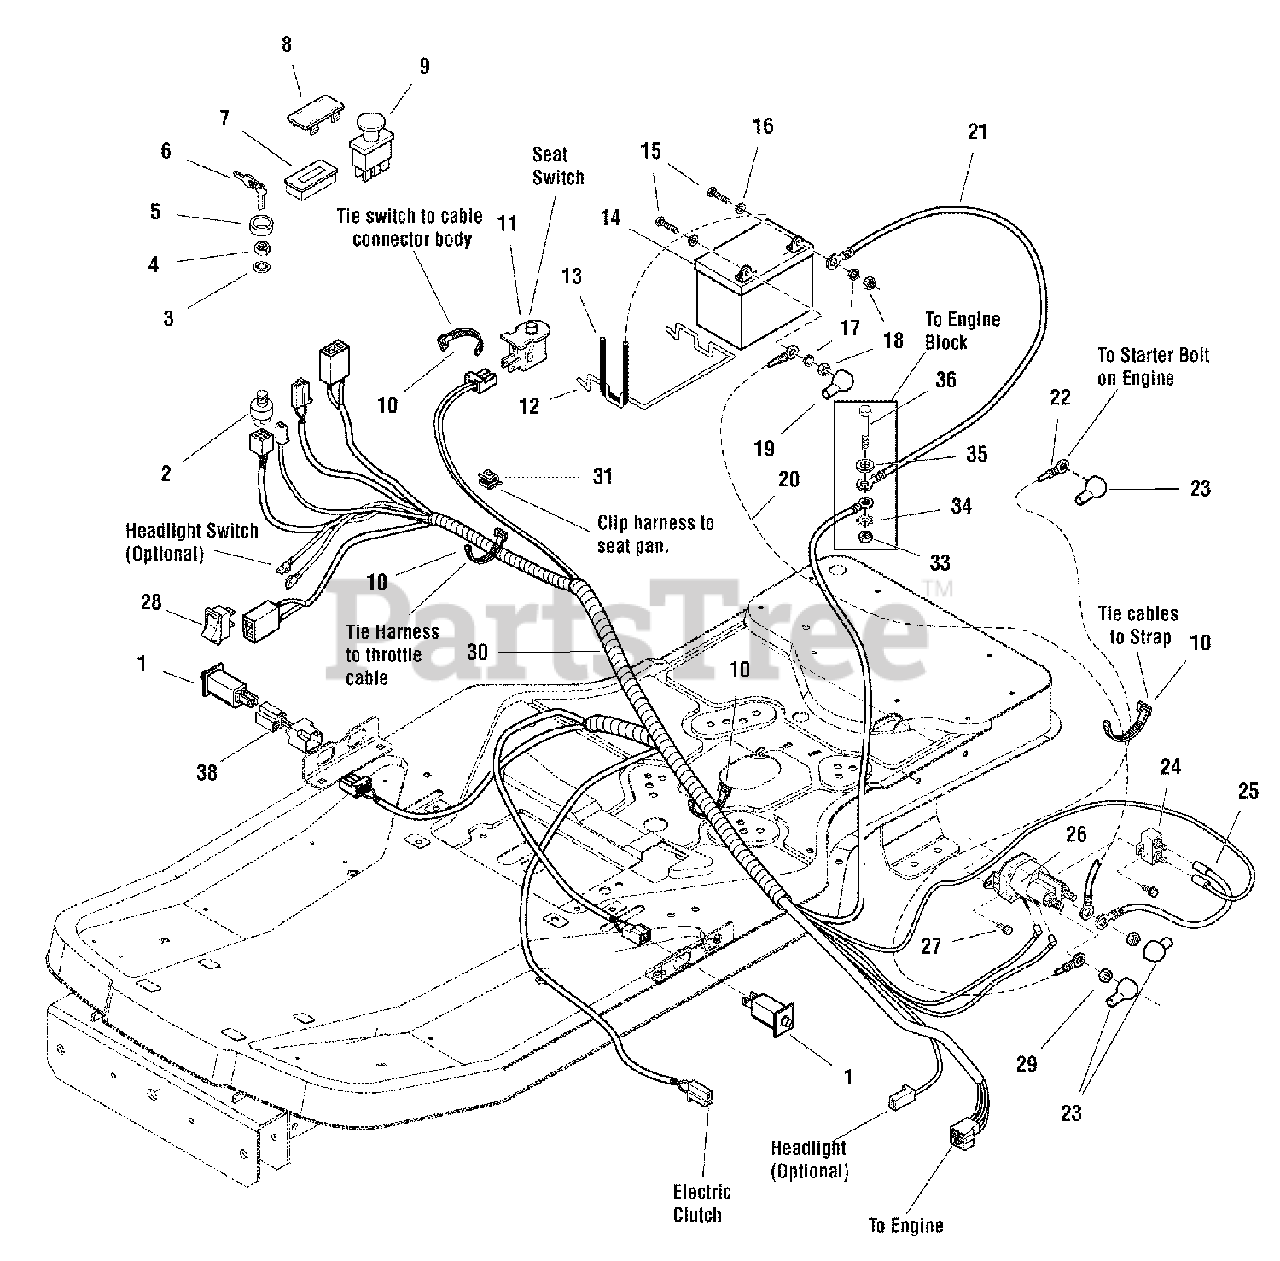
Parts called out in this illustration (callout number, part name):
1	SWITCH, Push Button
2	SWITCH ASSEMBLY, Ignition, 6 Pin Indak (W/Keys Ref. #6)
3	LOCKWASHER, Internal Tooth, 5/8 Thin
4	NUT, Hex Flange, 5/8-32 IGN SW Die Cast
5	COVER, Ignition Switch
6	KEYS
7	HOUR METER, No Alarms
8	PLUG, Hole
9	SWITCH, PTO, Push/Pull
10	TIE, Self Locking, .184 WD 7.31 LG
11	SWITCH, Push Button
12	BRACE, Battery, .19 DIA Wire
13	STRAP, Black Rubber, .19 SQ 7.88 OD Battery
14	BATTERY, 12 Volt 6 Cell 230 CCA
15	CAPSCREW, Hex Head, 1/4-20 x 3/4, G5
16	WASHER, 1/4, .27 ID x .62 OD x .05 THK
17	LOCKWASHER, Spring, 1/4
18	NUT, Hex, 1/4-20 NC-2B
19	BOOT, Insulator, Red PVC Warning
20	CABLE, # 6 x 10 LG, Red Two-Ring Terminals
21	CABLE, # 6 X 26 LG, Two-Ring Terminals
22	CABLE, # 6 x 15 LG, Two-Ring Terminals
23	COVER, Terminal Red PVC
24	BREAKER, Circuit, 12 Volt 20 AMP
25	WIRE, 12 Gauge, 7.9 LG
26	SOLENOID, Two 1/4-20 Terminals, Trombetta, Two Spade
27	SCREW, Hex Washer Head Taptite, 1/4-20 x 1/2
28	SWITCH, Electric Height of Cut
29	NUT, 1/4-20 Hex Serrated Flange
30	HARNESS, Wiring
31	CABLE, Clip
33	NUT, Hex Whiz Lock Flange, 5/16-18
34	LOCKWASHER, External Tooth, 3/8
35	WASHER, 5/16
36	CAPSCREW, Hex Head, 5/16-18 x 2, G5
38	WIRING ASSEMBLY, Jumper All Conditions Shutdown
